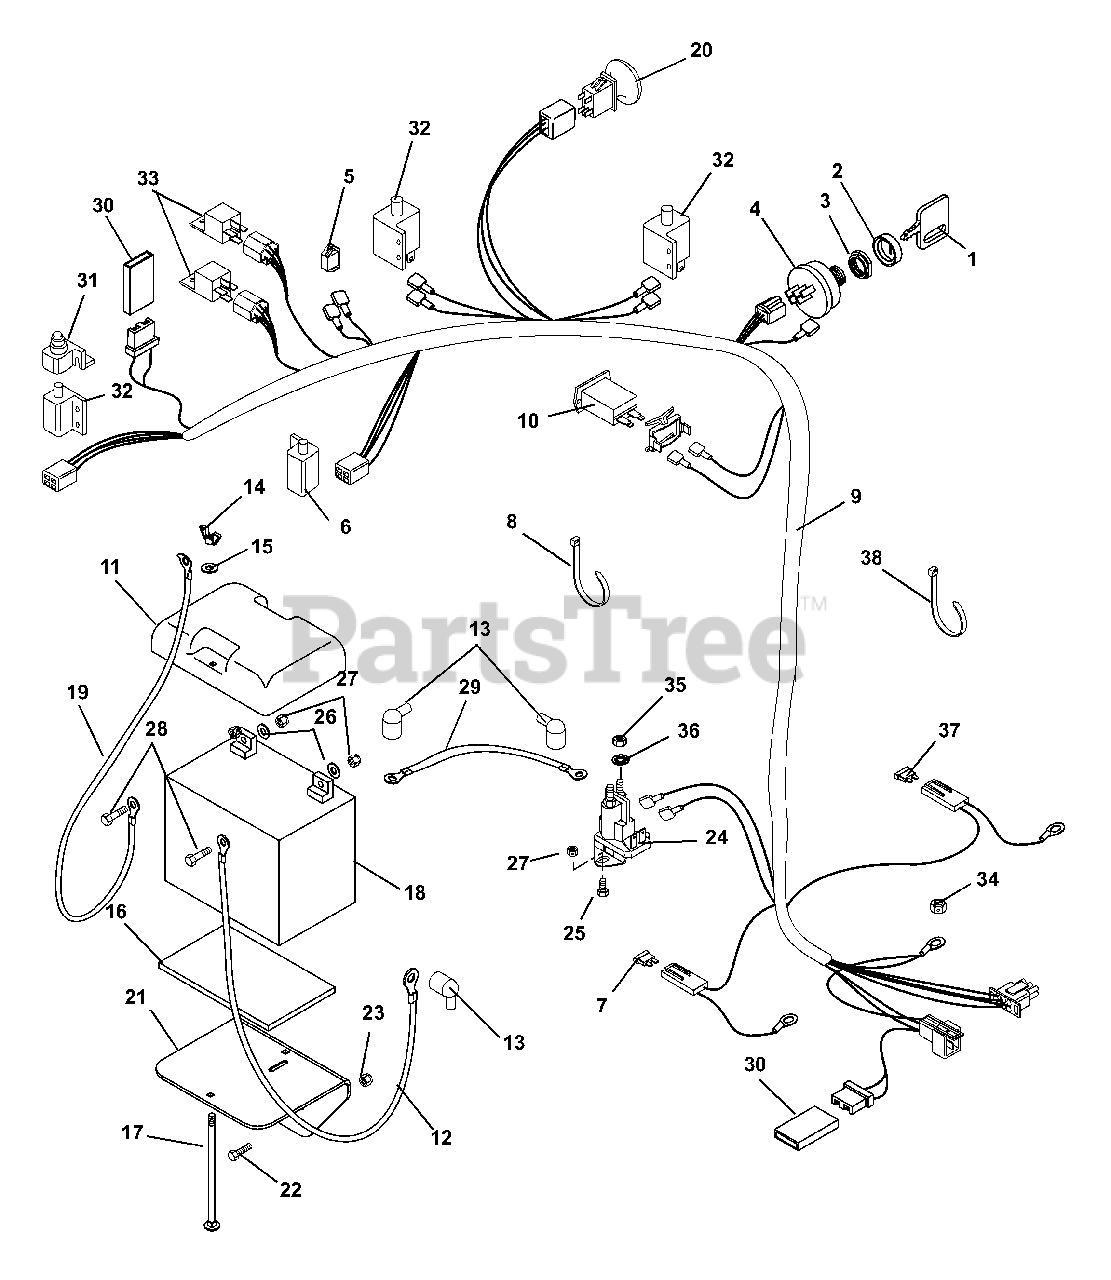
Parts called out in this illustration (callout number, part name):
1	KEY -W/CAP
2	CAP - IGNITION SWITCH
3	NUT- PANEL .562-24 GRECO
4	KEY SWITCH
5	LIGHT,INDICATOR
6	SWITCH,INTERLOCK
7	FUSE-25 AMP ATC TYPE
8	CABLE TIE LG 5-1/2
9	HARNESS - WIRE HYDRO ELEC-ERGO
10	HOUR METER - DIGITAL
11	COVER, BATTERY
12	START CABLE 22"
13	BOOT, EYELET TERMINAL
14	NUT-LK WING .250-20 YWZC
15	@WSHR-FL-STL.281X.62X.065 YWZC
16	PAD,BATTERY
17	BLT-RDHDSQNK .25-20X7.50 GR2YZ
18	BATTERY, 300 CCA 10U1L
19	CABLE-NEGATIVE BATTERY 24.00"
20	SWITCH, CLUTCH
21	WELDMENT, BATTERY TRAY
22	@BLT-HEX .38-16X1.00 GR5 YWZC
23	@NUT-LK-NYL .38-16 YWZC
24	SOLENOID
25	@BLT-HEX .25-20X.75 GR5 YWZC
26	@WSHR-FL-STL.281X.62X.065 YWZC
27	@NUT-SPNLK-FLG .25-20 YWZC
28	@BLT-HEX .25-20X.75 GR5 YWZC
29	STARTER CABLE 6.75"
30	DIODE, CONNECTOR SHELL
31	BOOT, RUBBER
32	SWITCH,INTERLOCK
33	RELAY
34	@NUT-LK-TOP-FLG .31-18 YWZC
35	NUT-JAM .31-24 YWZC
36	WSHR-LOCK INT .31 YWZC
37	FUSE 20AMP
38	TIE WRAP
